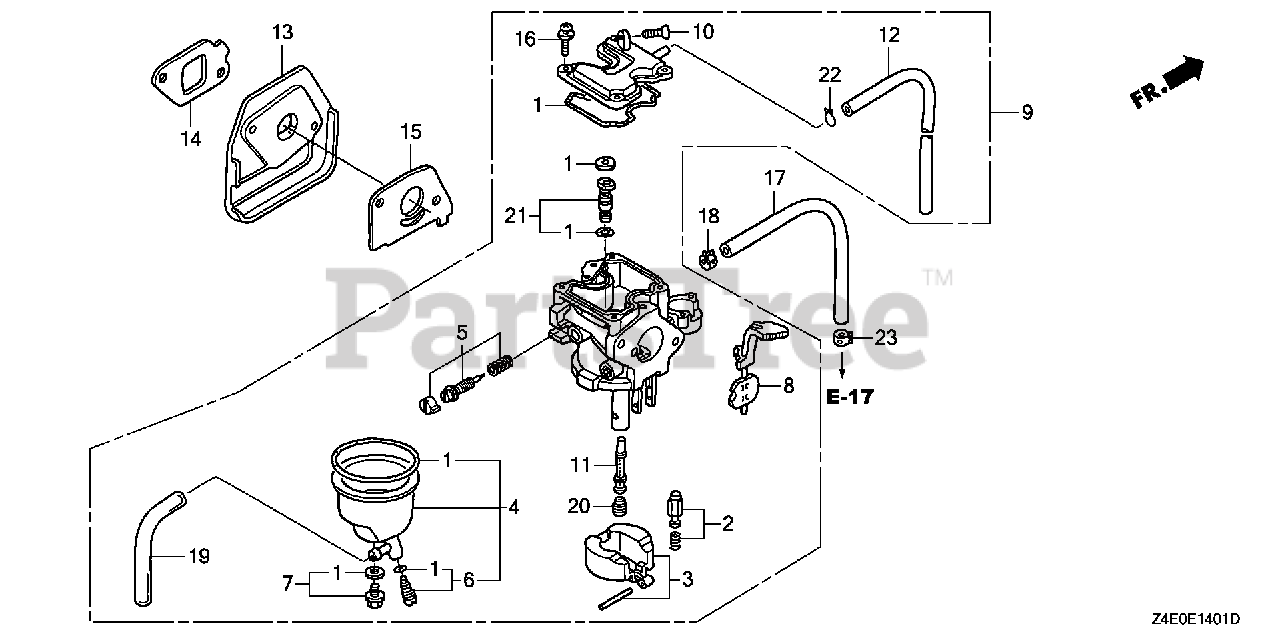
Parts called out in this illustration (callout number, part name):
1	GASKET SET (CARBURETOR NO.)
2	VALVE SET, FLOAT (SEAT NOT INCLUDED)
4	CHAMBER SET, FLOAT (CARBURETOR NO.)
6	SCREW SET, DRAIN (CARBURETOR NO.)
7	SCREW SET (CARBURETOR NO.)
8	LEVER SET, CHOKE
9	CARBURETOR ASSY. (BF33D C)
9	CARBURETOR ASSY. (BF33P A)
10	SCREW, THROTTLE STOP
11	NOZZLE, MAIN
12	TUBE, AIR VENT
13	INSULATOR, CARBURETOR
14	GASKET, INSULATOR
15	GASKET, CARBURETOR
16	SCREW-WASHER (4X12)
17	BULK HOSE, FUEL (4.5X3000) (4.5X400)
18	CLAMP, TUBE (D8.5)
19	BULK HOSE, VINYL (3.5X6.5X8000) (3.5X6.5X100)
20	JET, MAIN (#55)
20	JET, MAIN (#58)
20	JET, MAIN (#60)
21	JET SET, PILOT (#35)
22	CLIP, TUBE (B1 8)
23	CLAMP, TUBE (D8.5)
